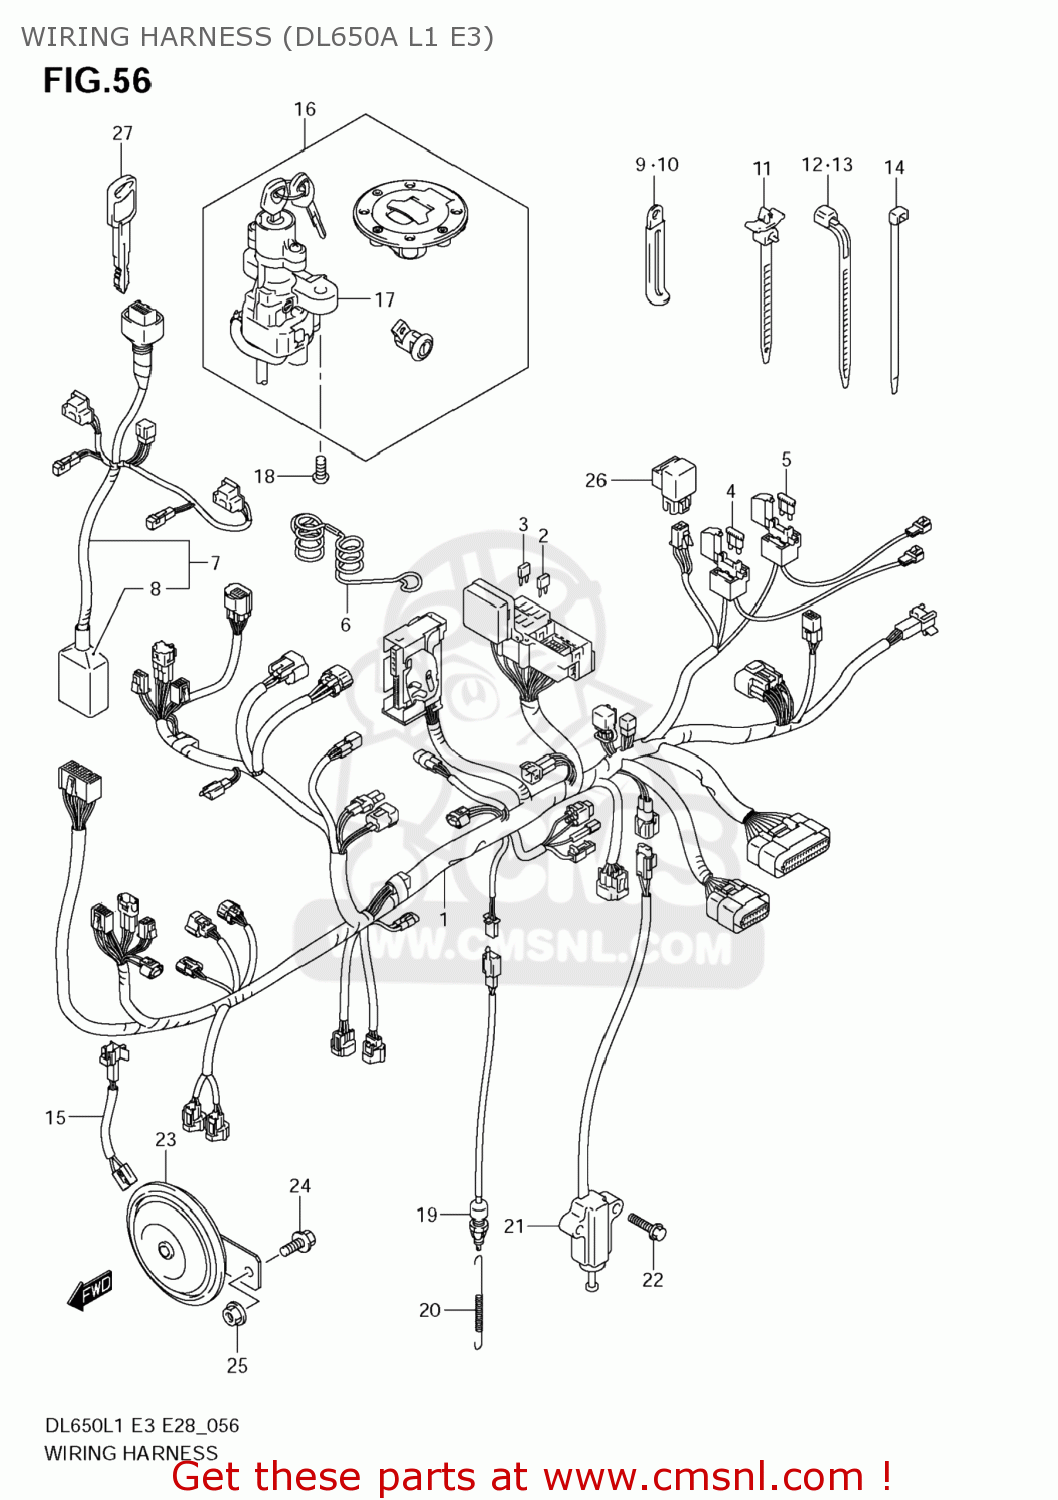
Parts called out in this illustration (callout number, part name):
1	HARNESS,WIRING NO.1
2	FUSE(10A)
3	FUSE(15A)
4	FUSE(40A)
5	FUSE(25A)
6	GUIDE,WIRING HARNESS
7	HARNESS,WIRING NO.2
8	COVER,CONNECTOR
9	CLAMP(L:45)
10	CLAMP(L:80)
11	CLAMP(L:120)
12	CLAMP(L:95)
13	CLAMP(L:125)
14	CLAMP(L:145)
15	WIRE,HORN LEAD
16	LOCK SET
17	LOCK ASSY,STEERING
18	BOLT(8X20)
19	SWITCH ASSY,STOP LAMP
20	SPRING
21	SWITCH ASSY,SIDE STAND
22	BOLT
23	HORN ASSY
24	BOLT
25	NUT
26	RELAY ASSY
27	KEY,BLANK
